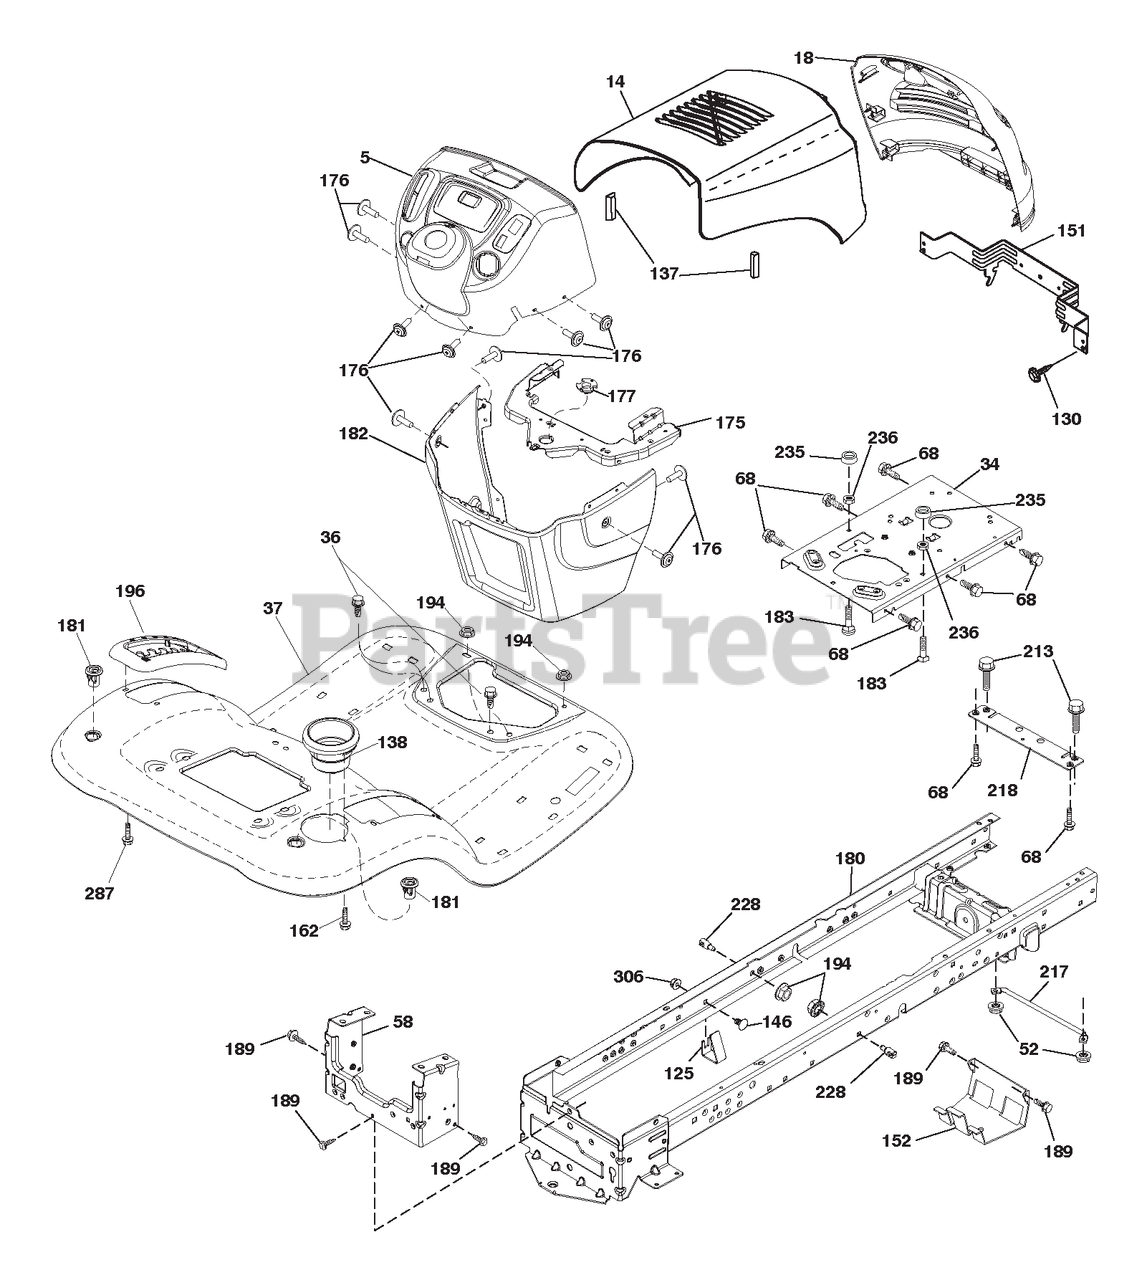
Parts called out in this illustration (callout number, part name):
34	PLATE.ENGINE.WELDED.CHASSIS
36	SCREW.5/16-18X3/4.SMGML.TAP/R
37	FENDER TLT W/CPH W/FW 422
52	Nut, Hex, Crownlock 5/16-18
58	DRAWBAR.UPPER.2PC.SML.FENDER
68	SCREW.THDROL.5/16-18 X 1/2TYTT
125	CLIP.FUEL.LINE
137	BUMPER.HOOD.LARGE. 1.75"
138	CUPHOLDER TL TEX 428
151	Bracket Pivot
152	SHIELD.BROWNING.W/TEX
162	SCREW.HEX.WSH.HI-LO.1/4X1/2UNC
175	CROSSMEMBER.LT
176	SCREW.#10-24X5/8.RND.QUDRX.GIM
177	BUSHING.STEERING.LT
180	CHASSIS
181	BUSHING MNT FEND CRGO BLK TEX
182	DASH LOWER.LT.CCS
183	BOLT.FIN.HEX.5/16-18 UNC X1-1/
189	SCREW.5/16-18X3/4.SMGML.TAP/BL
194	Nut, Lock Hex Flange 5/16-18 u
196	CONSOLE ASM.DECKLFT.BL/RBT.TLT
213	BOLT.HEX.HD.1/4-20UNC X 3/4
217	ROD.PIVOT.HOOD
218	X-PIECE.HOOD.STOP.NON/STEALTH
228	STUD.FASTNER.W/'D'ANTI-ROTATIO
235	SPACER.FENDER
236	NUT.CENTER LOCK.5/16-18 UNC
287	SCREW.HEX.WASHEAD.1/4-20 X 3/8
306	Nut, Hex, Flangelock 3/8-16
